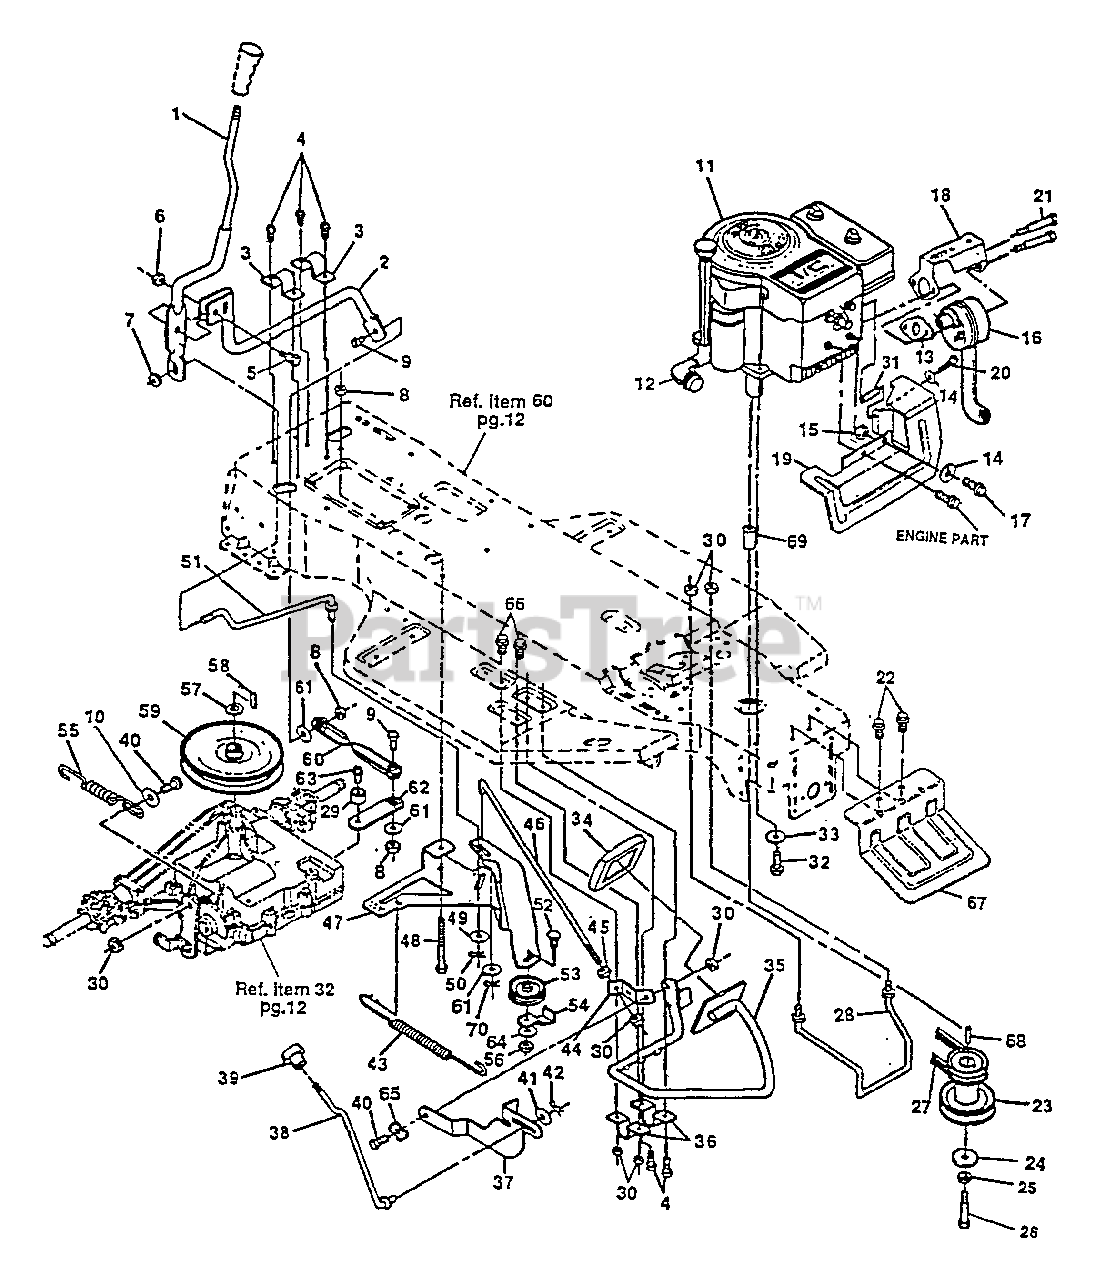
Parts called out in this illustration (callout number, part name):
1	Tube Assembly, Shift Pivot
2	Tube Assembly, Shift
3	Clip, Shift Lever
4	Screw, Hx Hd, Wshr Tap, 5/16-18 x 1/2 in.
5	Shoulder Bolt
6	Nut, Hx, Ctrlk, 1/4-20 Thd.
7	Nut, Hx, Nylon, Lock 3/8-16 Thd.
8	Nut, Hx, Ctrlk, 3/8-16 Thd.
9	Screw, 3/8-16 x 1-1/4 In.
11	Engine 12.5 Horsepower B&S
12	Elbow, 900, 3/8 In.
13	Gasket, Muffler
14	Washer, Split Lock
15	Nut, Hex 5/16-18 Thd.
16	Muffler, Round 5" Diameter
17	Screw, Wa Tap, 1/4-20 x 7/8 In.
18	Shield, Muffler
19	Heat Shield, Engine
20	Screw, Hex Hd, 1/4-20 x 3-1/2 In.
21	Bolt, Shoulder, 5/16-18 x 4-1/3 In.
22	Screw, Wa Tap, 5/16-18 x 1/2 In.
23	Pulley, Engine
24	Washer, Pilot
25	Washer, Split, Lock 7/8 In.
26	Screw, Hx Hd, 7/16-20 X 5 In.
27	V-Belt, 90 In. Long
28	Belt Guide
29	Washer, Special
30	Nut, Hex, Ctrlk, 5/16-18 Thd.
31	Spacer, Heat Shield
32	Screw, Hex Hd Tap, 3/8-16 x 1-1/4 In.
33	Washer, 3/8 In.
34	Pad, Clutch/Brake, Molded
35	Assembly, Clutch/Brake Arm
36	Bracket, Clutch/Brake Arm
37	Lever, Park Brake
38	Rod, Parking Brake
39	Knob, Parking Brake
40	Shoulder Bolt, 5/16-18 Thd.
41	Washer, 9/16 In.
42	Cotter Pin
43	Spring, Clutch
44	Bracket, Brake Rod
45	Nut, Hx, Keps, 5/16-18 Thd.
46	Rod, Clutch
47	Arm, Idler
48	Shoulder Bolt, 3/8-16 Thd.
49	Washer, Flat, 13/32 In.
50	Hairpin
51	Rod, Shift-On-The-Go
52	Carriage Bolt, 3/8-16 x 2 In.
53	Idler Sheave, Backside
54	Belt Retainer
55	Spring, Brake
56	Nut, Flange, 3/8-16 Thd
57	Retaining Ring
58	Key, Woodruff, #606
60	Shift Link
61	Washer, Flat, 13/32 In.
62	Shift Lever, Transaxle
63	Screw, Hx Hd, 1/4-28 X 3/4 In.
64	Washer, Flat, 13/32 in.
65	Washer, Wave
66	Screw, 5/16-18 x 5/8 In.
67	Deflector, Exhaust
68	Key, Square 1/4
69	Spacer, Engine Pulley
70	Pin, Cotter
